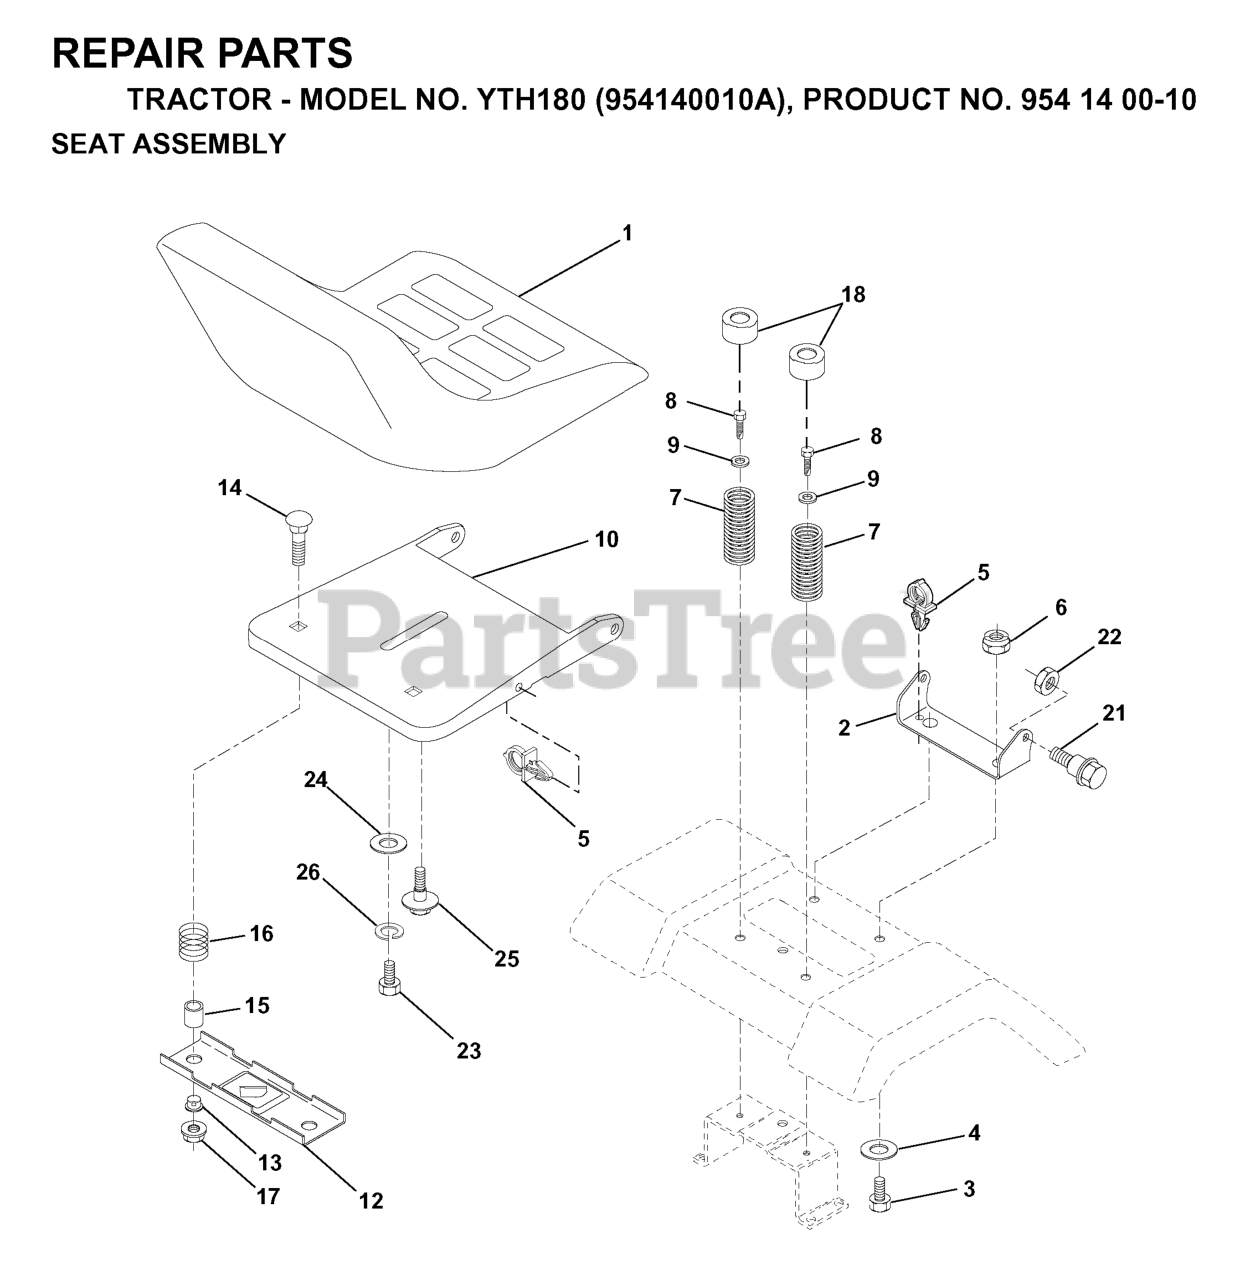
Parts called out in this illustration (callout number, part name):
1	SEAT, GRAY
2	SEAT PIVOT BRKT
3	BOLT
6	NUT
7	SPRING COMPRESSION
8	SCREW GTV
9	WASHER
10	PAN, SEAT
12	BRKT SWITCH
14	Bolt Rdhd. Sht. Nk 1/4-20 x 1-3/8
15	SPACER SPLIT
16	SPRING COMPRESSED
17	NUT T
18	CAP SPRING
21	BOLT SHOULDER 5/16-18
22	NUT.71038.31-18.HEX.NYLOCK
23	BOLT
25	BOLT,SHOULD
26	LOCKWASHER
